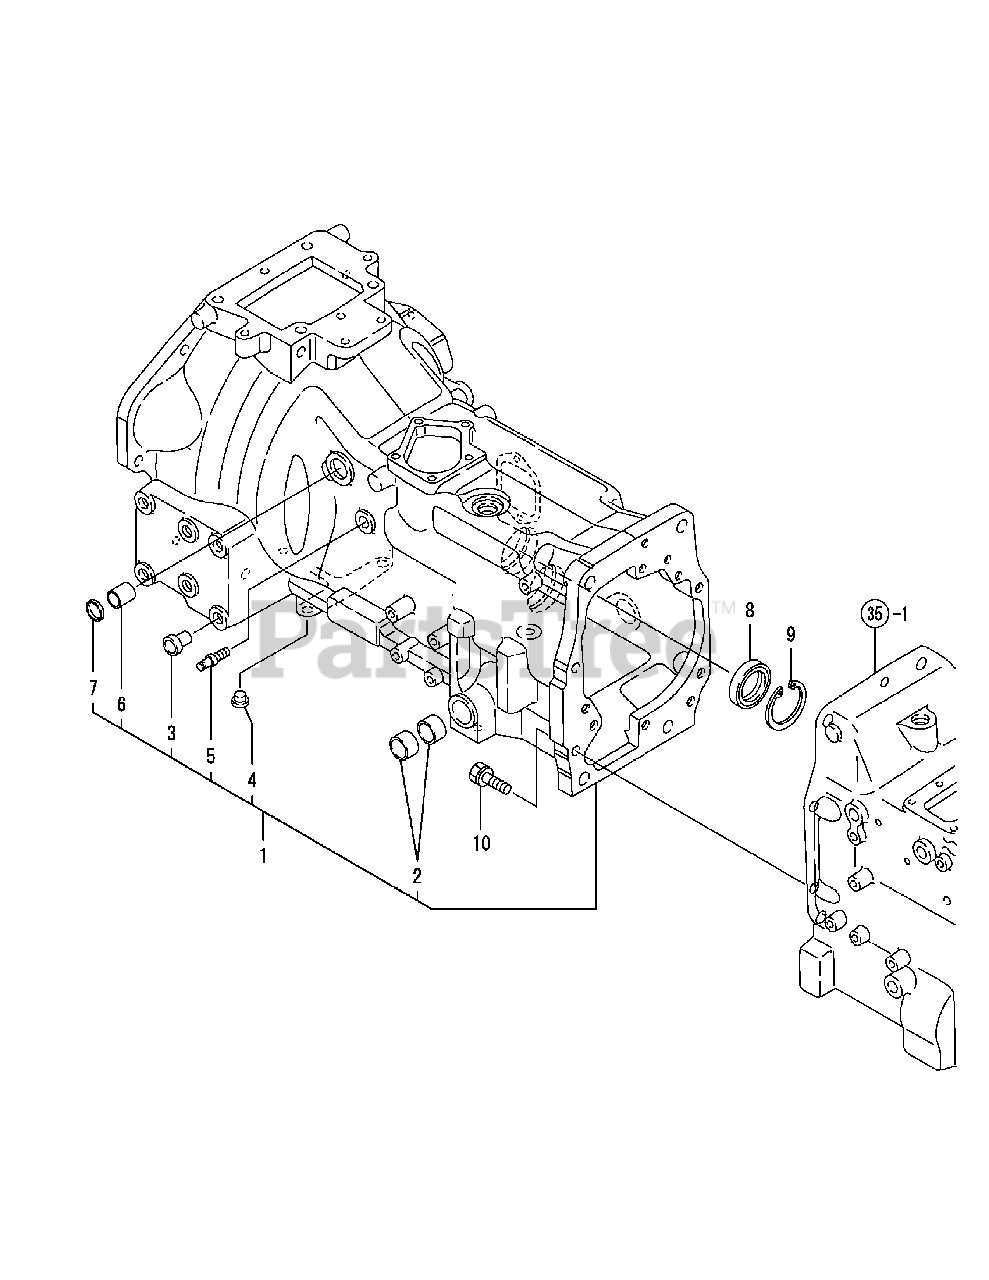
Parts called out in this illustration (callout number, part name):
1	HOUSING ASSY, CLUTCH
7	SEAL G202604,OIL
8	SEAL TC40 58 12
